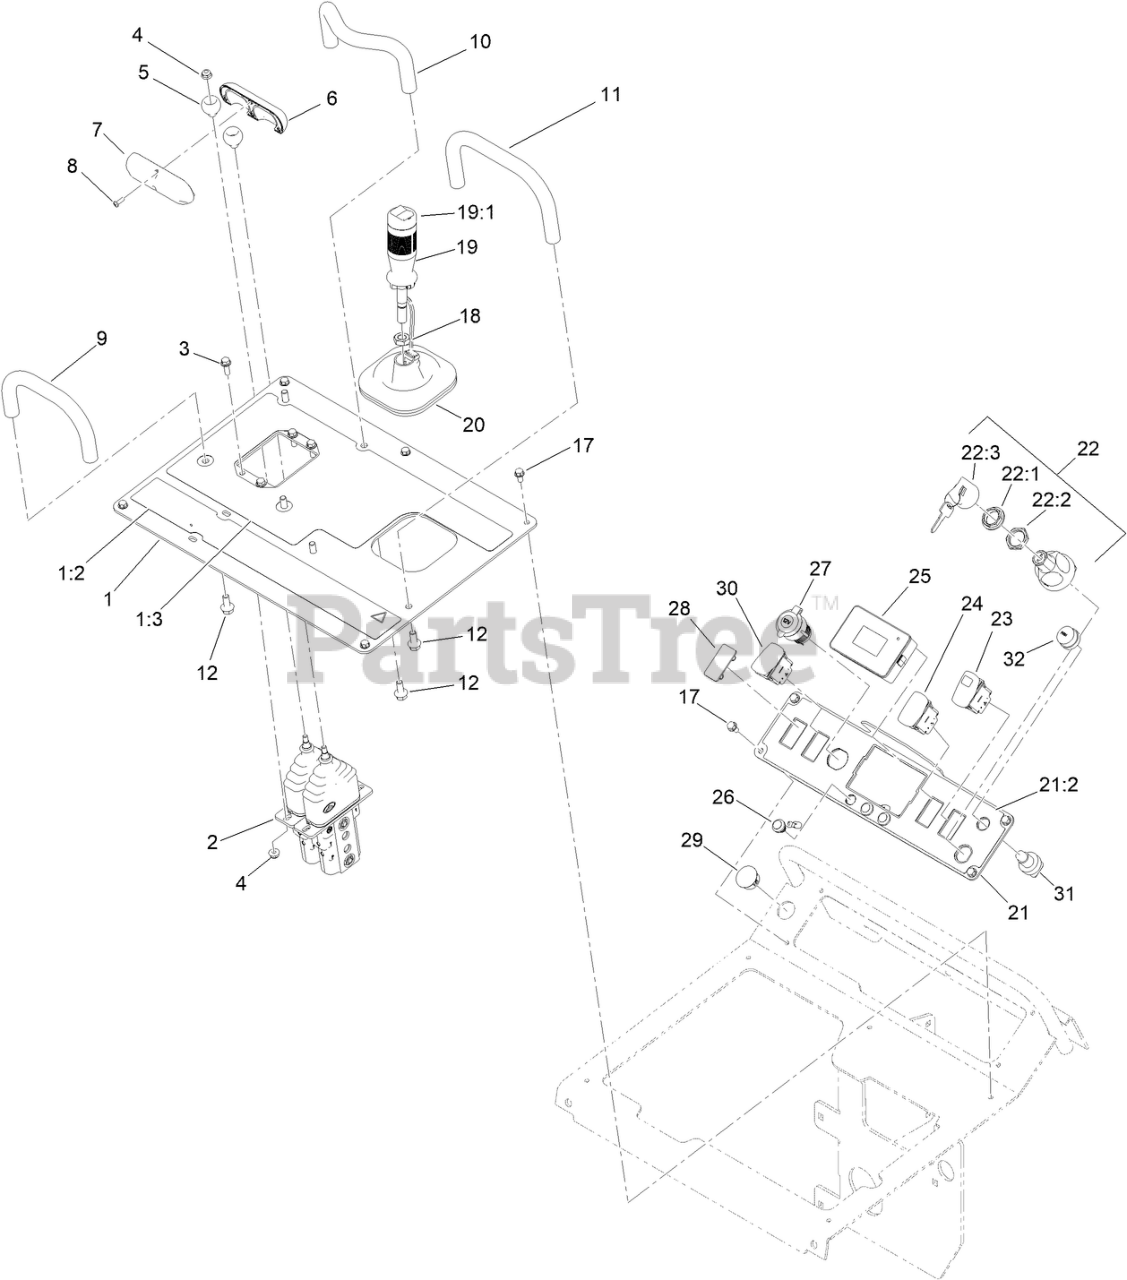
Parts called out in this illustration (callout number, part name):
1	PLATE ASM-CONTROLS
1:2	DECAL-SAFETY
1:3	DECAL-CONTROLS
2	VALVE-CONTROL (TRACTION)
3	SCREW-HHF
4	NUT-HF
5	BALL-TRACTION
6	HANDLE-CONTROL
7	HANDLE-TRACTION
8	SCREW
9	BAR-REFERENCE
10	BAR-REFERENCE
11	BAR-REFERENCE
12	SCREW-HHF
17	SCREW-HWH
19	HANDLE-AUXILIARY ASM
19:1	BOOT-SWITCH, JOYSTICK
20	BOOT-JOYSTICK
21	PLATE ASM-CONSOLE
21:2	DECAL-CONSOLE
22	IGNITION SWITCH ASM
22:1	NUT-HEX
22:2	NUT-FACE, M22 (PLASTIC)
22:3	SET-KEY, IGNITION
23	SWITCH-ROCKER, ON-NONE-(ON)
24	SWITCH-ROCKER,(ON)-OFF-(ON)
25	TDM 2002
26	SWITCH-PUSHBUTTON
27	RECEPTACLE-12V
28	PLUG-HOLE
29	PLUG-DOME
30	SWITCH-ROCKER, ON - NONE - ON
31	SWITCH-HORN
32	NUT-WEATHERPROOF
